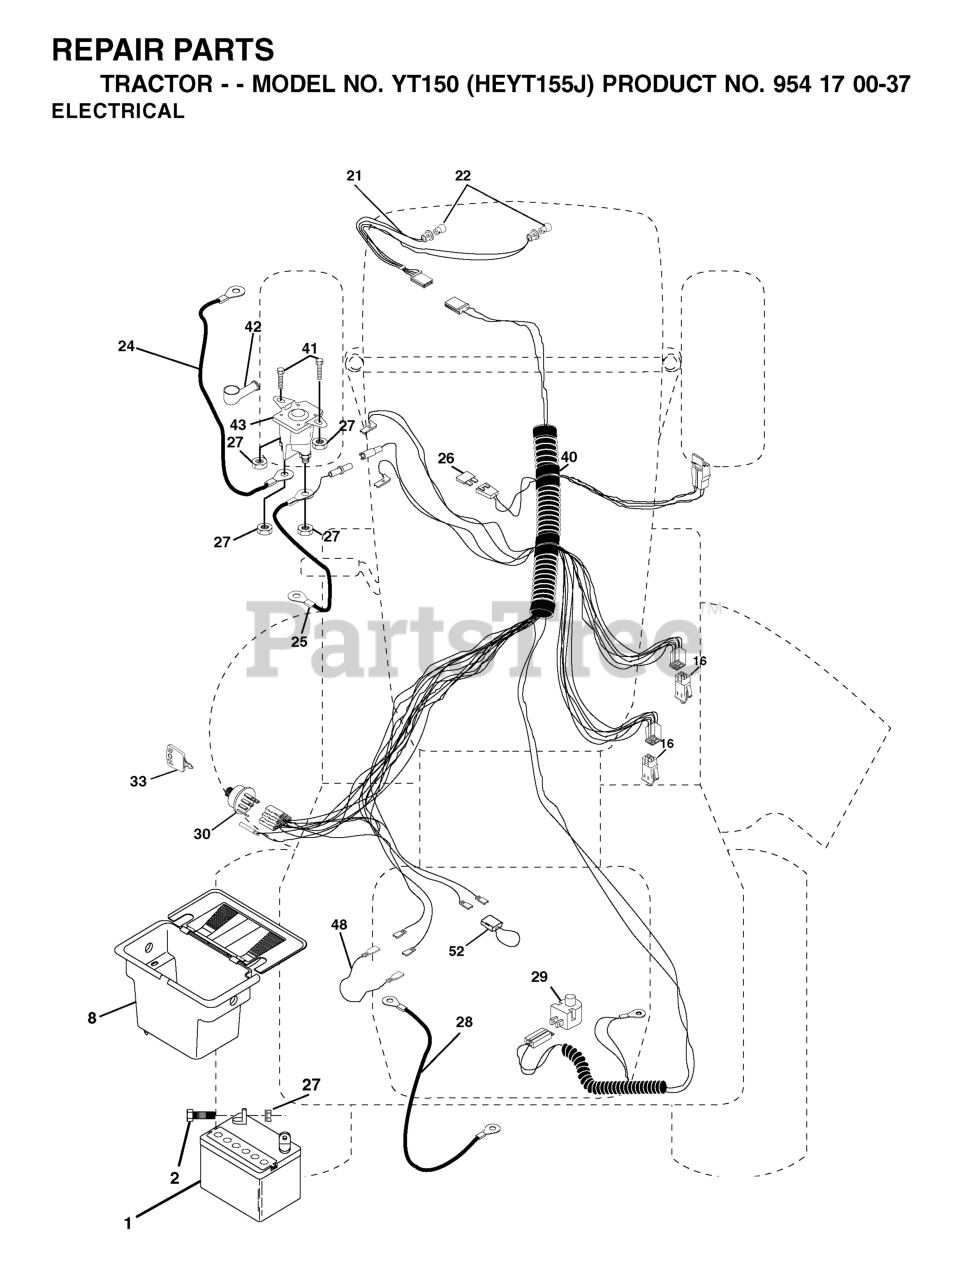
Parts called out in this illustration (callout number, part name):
1	BATTERY 12 VOLT 25 AMP
2	BOLT.HEX.1/4.X.3/4.DICHROMATE
8	CASE BATTERY MECH HINGE
16	SWITCH INTERLOCK
24	BATTERY CABLE GT
25	CABLE BATTERY
26	FUSE 20AMP
27	NUT
28	CABLE T
29	RP.SWITCH.PLUNGER.NC.GRAY
30	IGNITION SWITCH
33	KEY MLD GEN DELTA
40	CABLE, IGN. HARNESS
41	BOLT
42	TERMINAL COVER
43	SOLENOID
48	ADAPTER.AMMETER
52	WIRE PROTECTION LOOP
